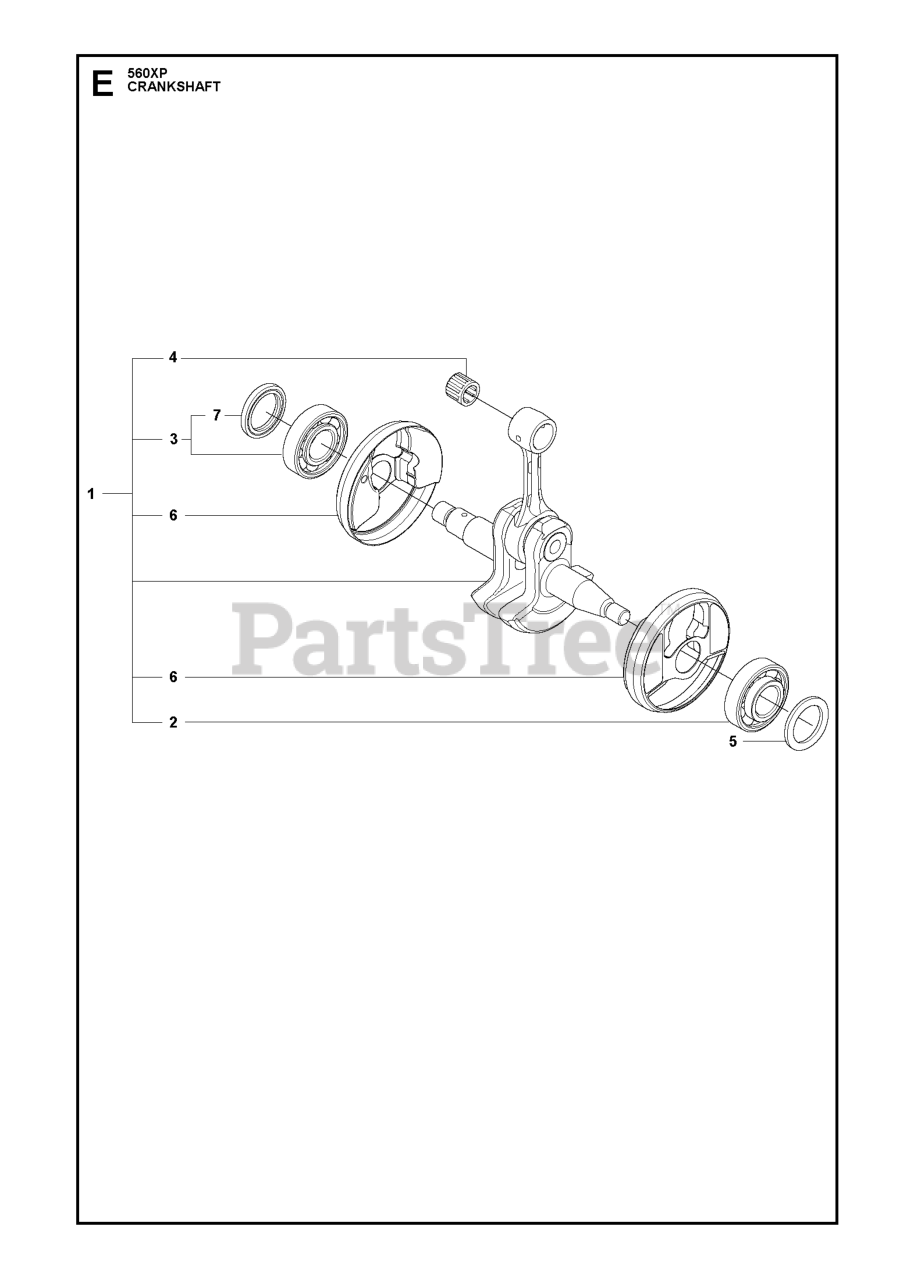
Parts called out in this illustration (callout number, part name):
2	BALL BEARING
3	BALL BEARING
4	NEEDLE BEARING
5	RADIAL SEAL
6	CUP
7	RADIAL SEAL
